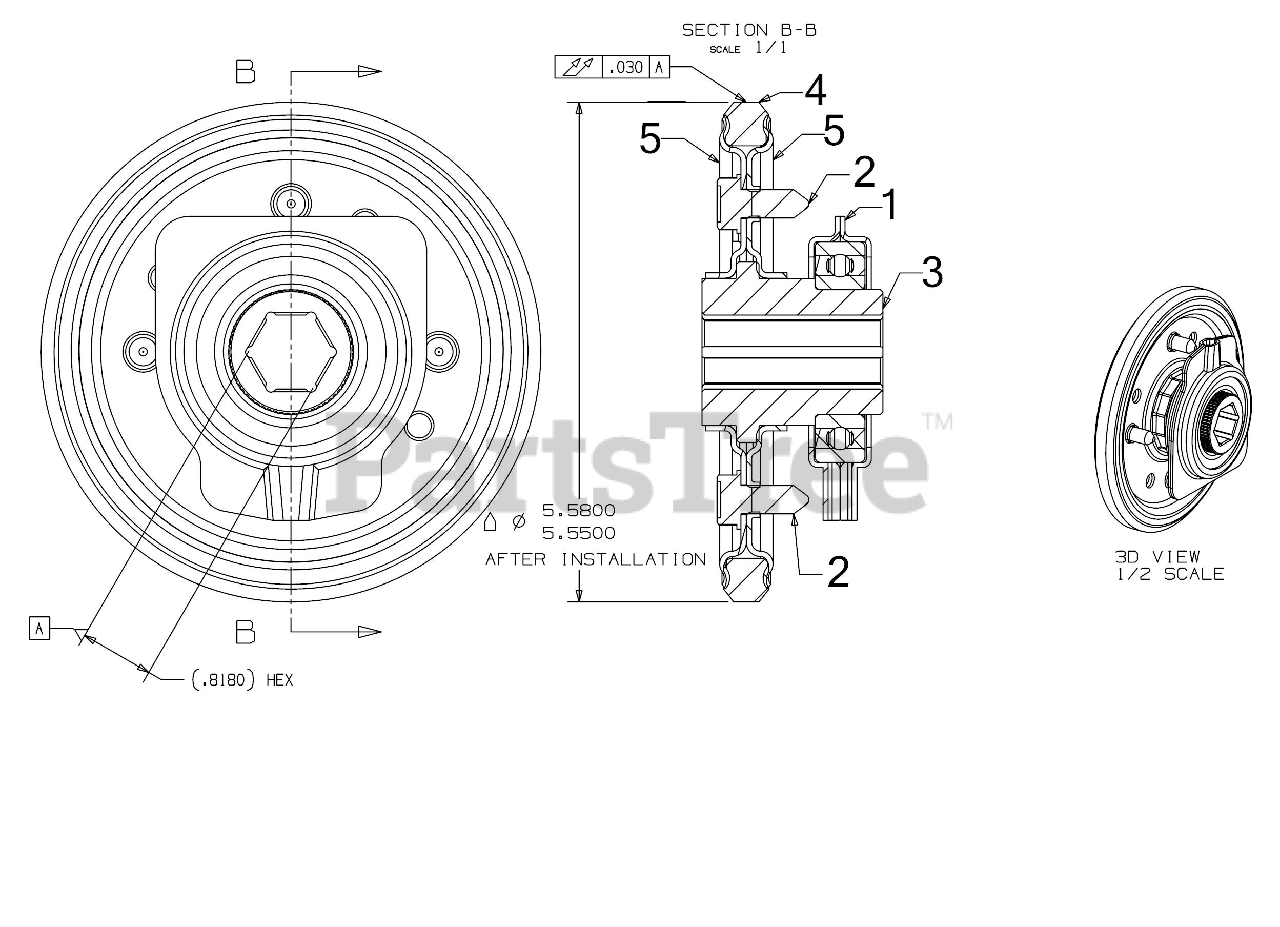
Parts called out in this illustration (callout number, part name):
1	FRICTION WHEEL BEARING ASSEMBLY
2	SCREW 5/16-18 x .750
3	FRICTION WHEEL HUB
4	FRICTION WHEEL 5.50OD
5	FRICTION PLATE
